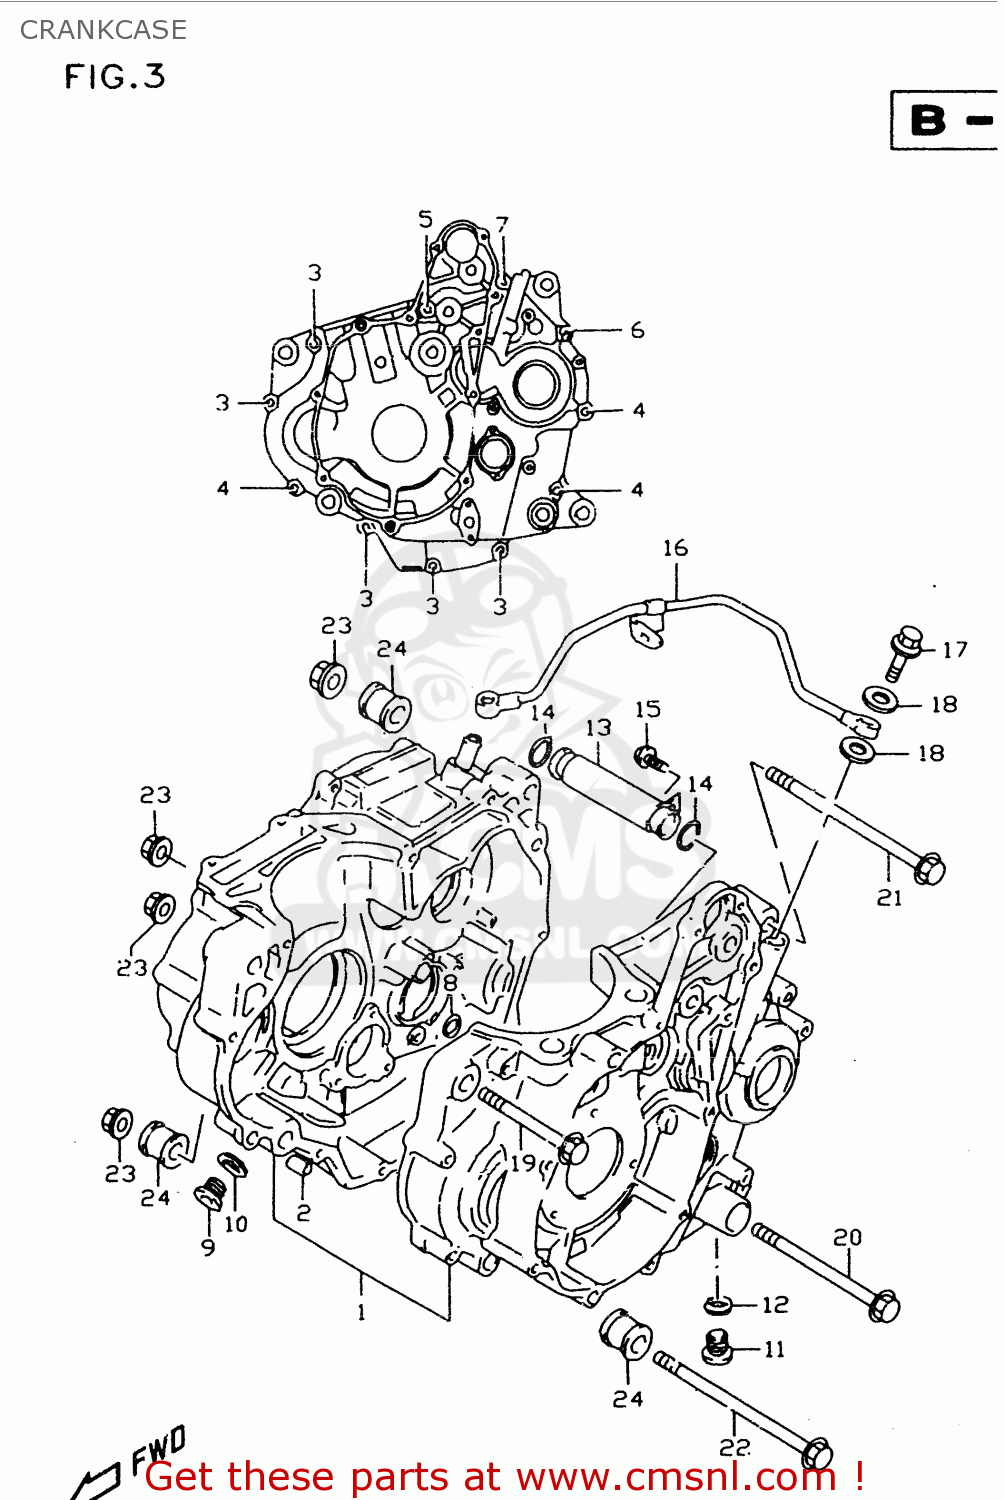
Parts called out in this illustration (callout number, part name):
1	CRANKCASE SET
2	PIN
3	BOLT
4	BOLT
5	BOLT
6	BOLT
7	BOLT
8	O-RING
9	PLUG,14X12
10	GASKET(13.8X18.8X4.8) (NAS)
11	BOLT
12	GASKET(12.1X16.2X3.7) (NAS)
13	PIPE,T/M OIL INNER
14	O RING(D:2.4,ID:15.8)
15	BOLT
16	PIPE,MISSION OIL OUTER
17	BOLT UNION
18	GASKET 8.2X14X1 (NAS)
19	BOLT 10X85
20	BOLT(10X101.5)
21	BOLT(10X115)
22	BOLT(10X143)
23	NUT
24	SPACER,ENGINE MOUNTING
